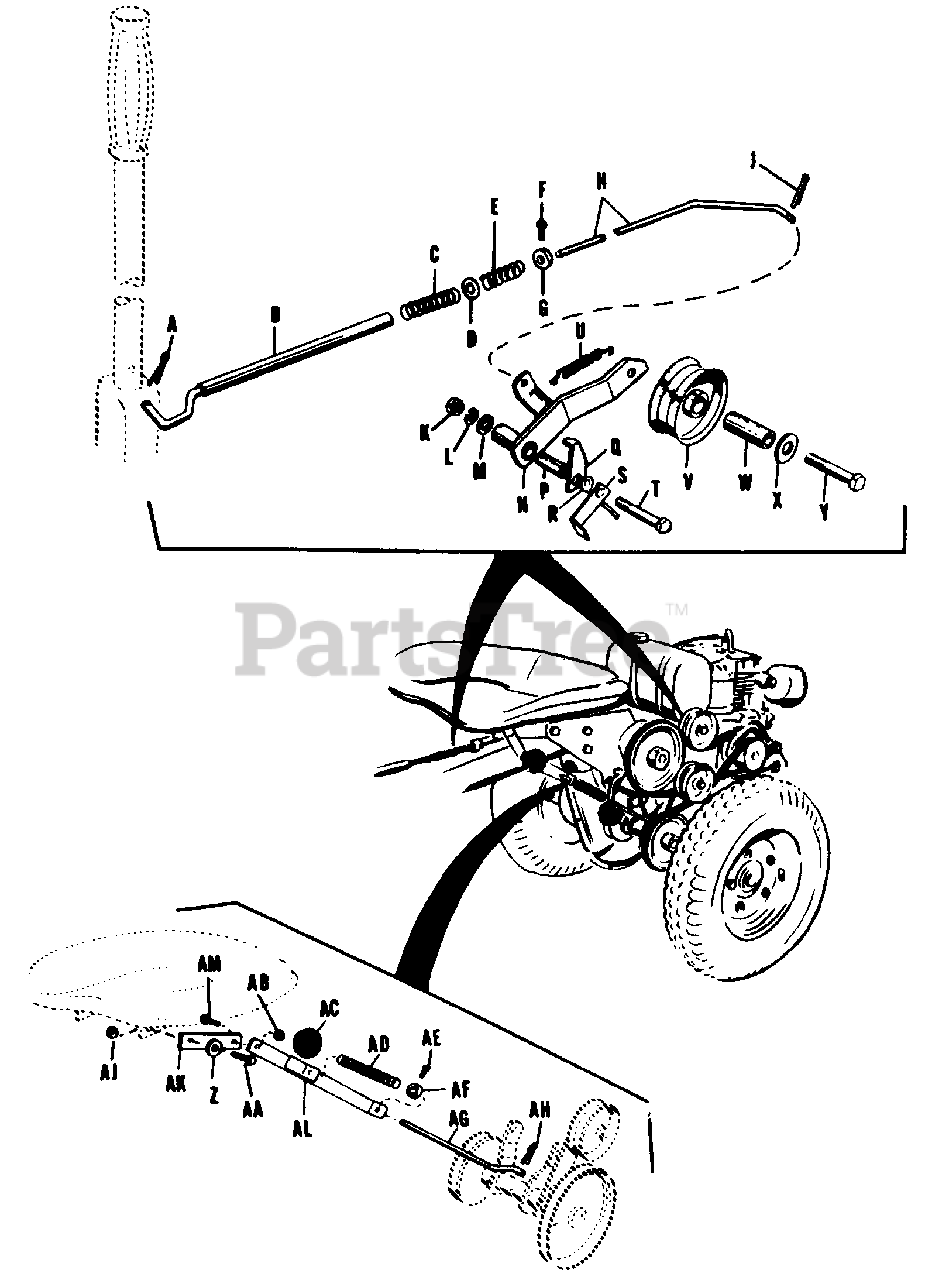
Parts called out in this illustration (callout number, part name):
A	Pin, Cotter, 3/32 x 5/8"
B	Rod, Front Clutch Assembly
D	Washer, Plated, 5/16"
F	Set Screw, Sq. Hd., 1/4-20 x 3/8"
G	Collar, Set
H	Rod, Rear Clutch
J	Pin, Cotter, 3/32 x 5/8
K	Nut, Full Hex, 3/8-16
L	Washer, Lock 3/8
M	Washer, Plain, 3/8
N	Lever Assembly, Idler
Q	Stop, Lever
R	Pin, Lock
S	Guide, Belt
T	Screw, Hex Cap, 3/8-16 x 2 3/4"
V	Pulley, Idler
W	Race, Inner Bearing
X	Washer, Plain, 3/8"
Y	Screw, Hex Cap, 3/8-16 x 2"
Z	Washer, Plain, 3/8"
AA	Screw, Hex Cap, 3/8-16 x 3/4
AB	Lock-nut 3/8-16
AE	Screw, Sq. Hd. Set, 1/4-20 x 3/8"
AF	Collar, Set
AG	Rod, Clutch
AH	Pin, Cotter, 3/32 x 5/8"
AJ	Nut, Lock 3/8-16
AL	Guide Assembly
AM	Screw, Hex Cap, 3/8-16 x 1"
